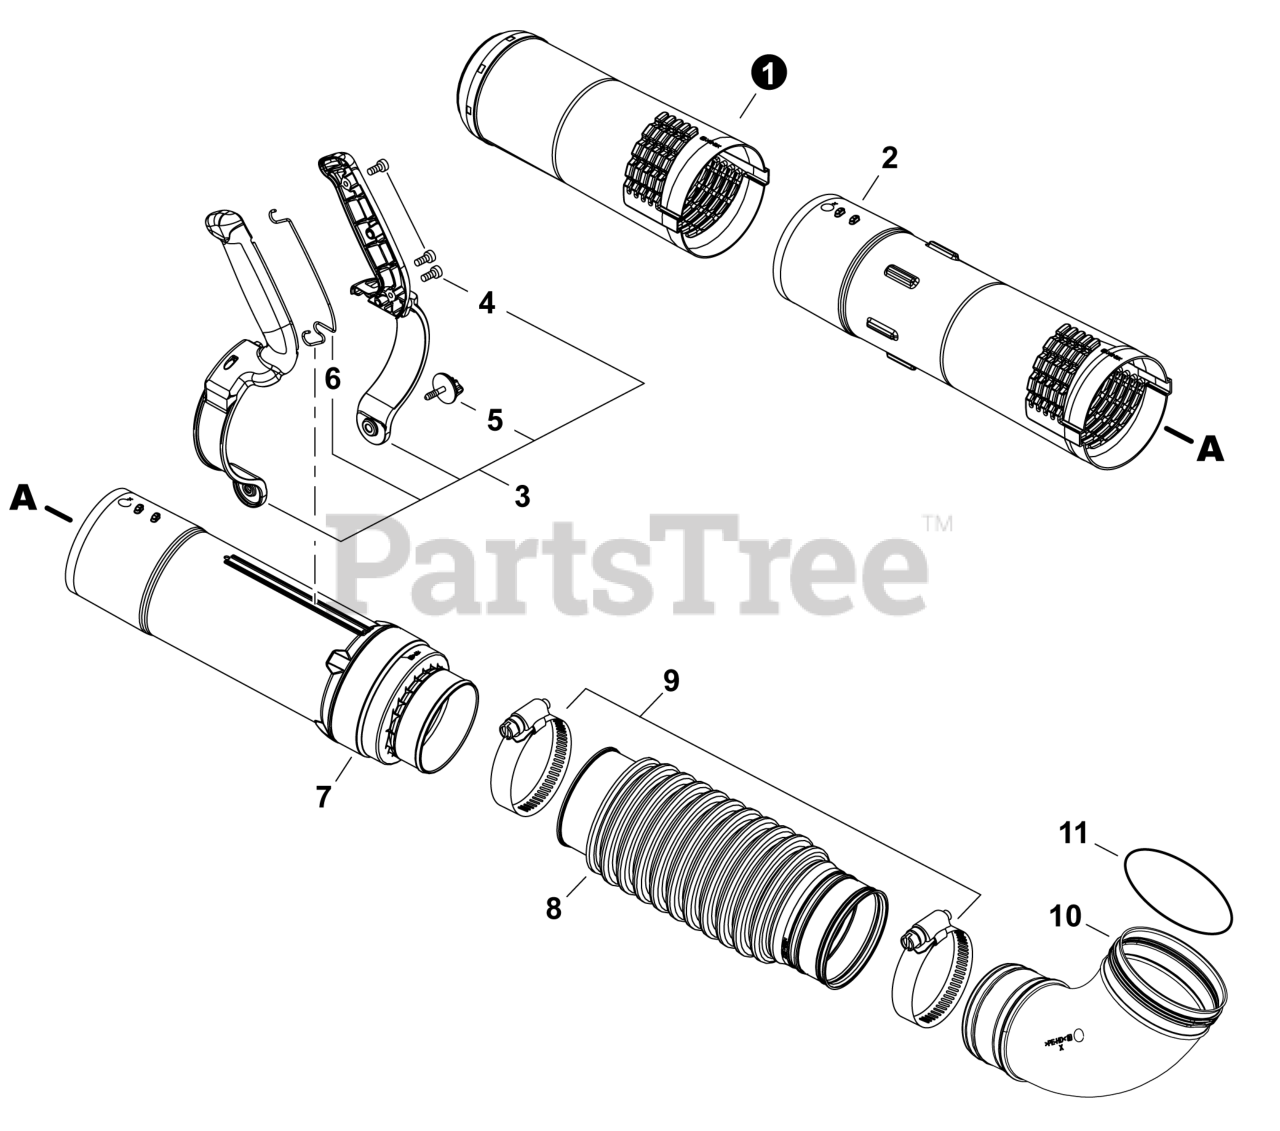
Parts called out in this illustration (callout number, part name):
1	TUBE, BLOWER - NOZZLE
2	TUBE, BLOWER - STRAIGHT
3	HANDLE KIT - BLOWER TUBE
4	BOLT, TORX 4x12
5	KNOB, FASTENER
6	PLATE, GROUND
7	TUBE, BLOWER - SWIVEL
8	TUBE, BLOWER - FLEXIBLE
9	CLAMP - BAND
10	TUBE, BLOWER - ELBOW
